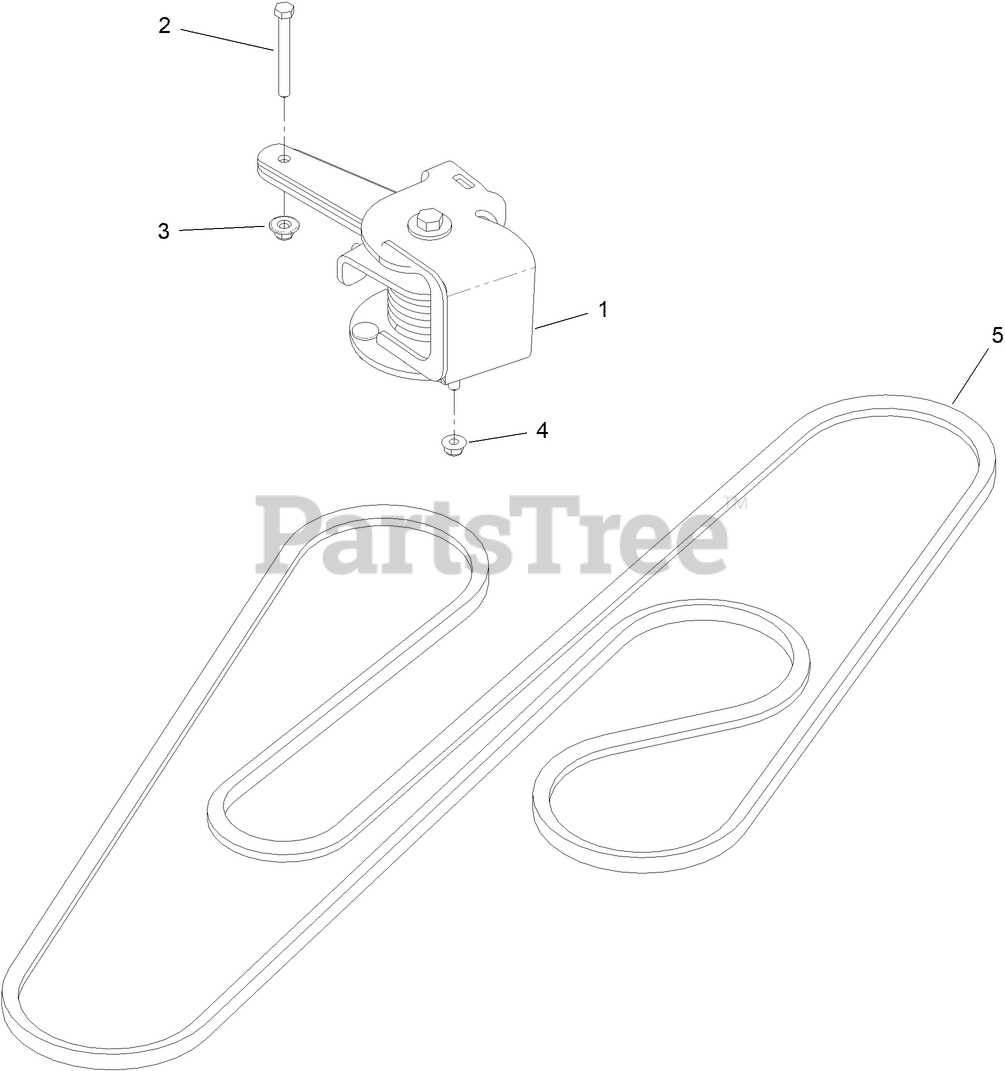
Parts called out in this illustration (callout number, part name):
1	GS TORSION IDLER ASM II
2	SCREW-HH
3	NUT-FLANGE, NI
4	NUT-HF, NI
5	GS 60 DECK BELT-V
